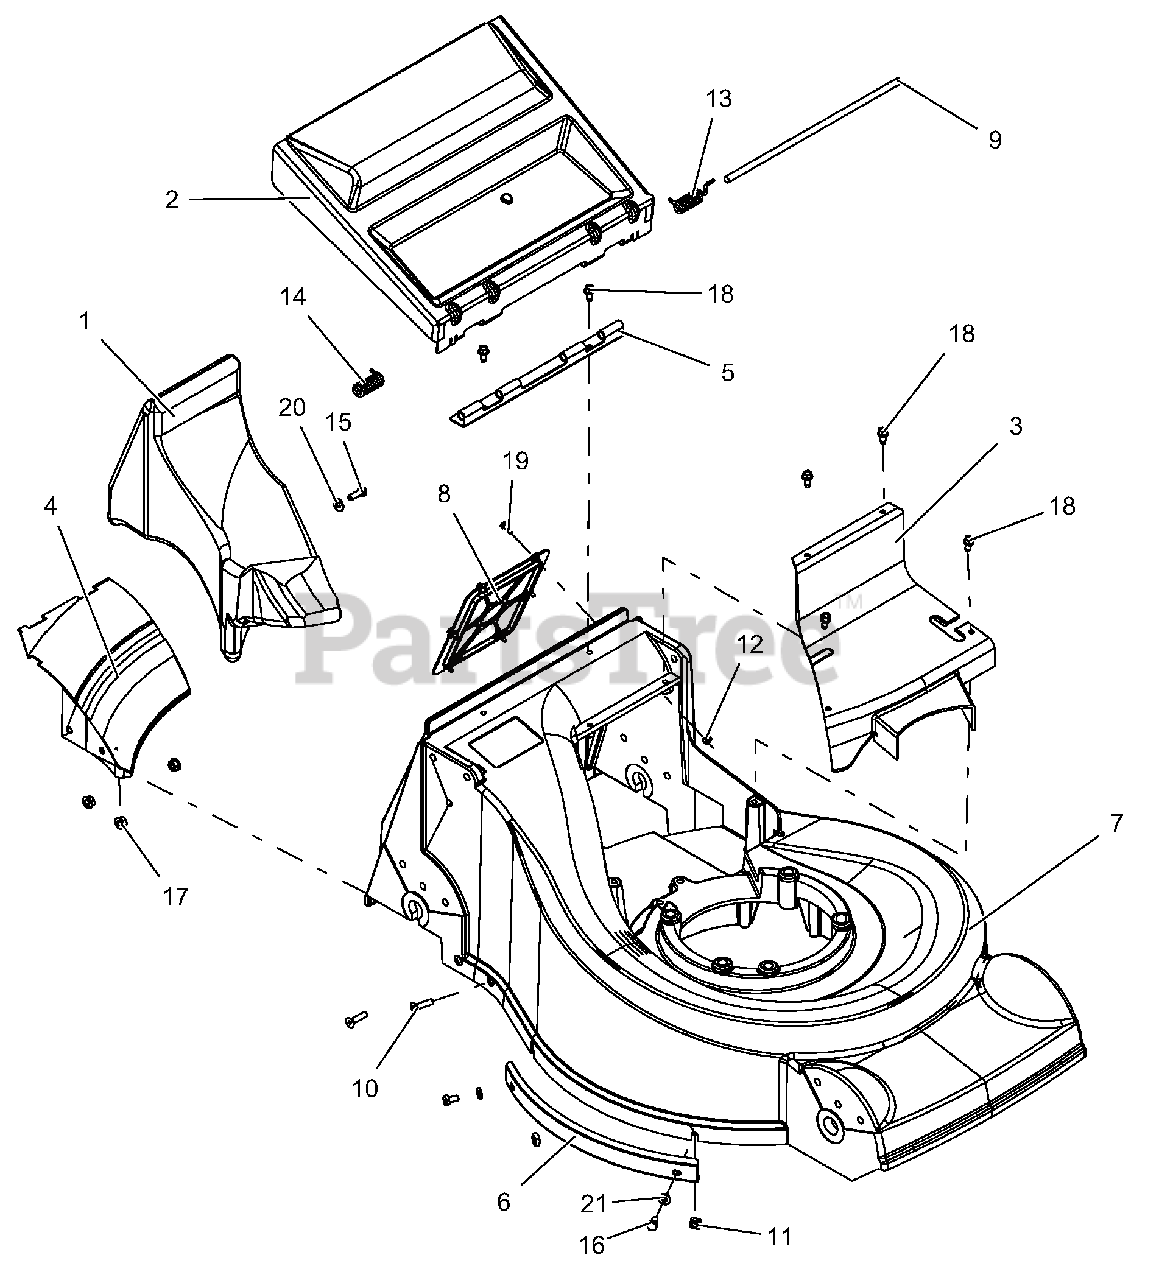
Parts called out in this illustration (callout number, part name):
1	PLUG, MULCH
2	DOOR, DISCHARGE
3	COVER, FRONT
4	CHUTE, DISCHARGE
5	HINGE, DISCHARGE DOOR
6	GUARD, EDGE
7	DECK, MOWER 21"
8	PANEL, ACCESS
9	PIN, DISCHARGE DOOR
10	SCR, MACHINE .25-20 X .875 FLATHD
11	NUT, SQUARE - .25-20 YWZC
12	NUT-LK-NYL #8-32 YWZC
13	SPRG, TORSION - DOOR LH
14	SPRG, TORSION - DOOR RH
15	BLT-HEX .25-20X.75 GR5 YWZC
16	BLT-HEX .25-20X.50 GR5 YWZC
17	NUT, LK-TOP-FLG .25-20 YWZC
18	SCR-TAP .25-20X.50 HWH TRZ YW
19	SCR-TAP 8-32X.50 HWH TR YWZC
20	WSHR-FL-STL.281X.62X.065 YWZC
21	WSHR-FL-STL.250X.562X.049YWZC
